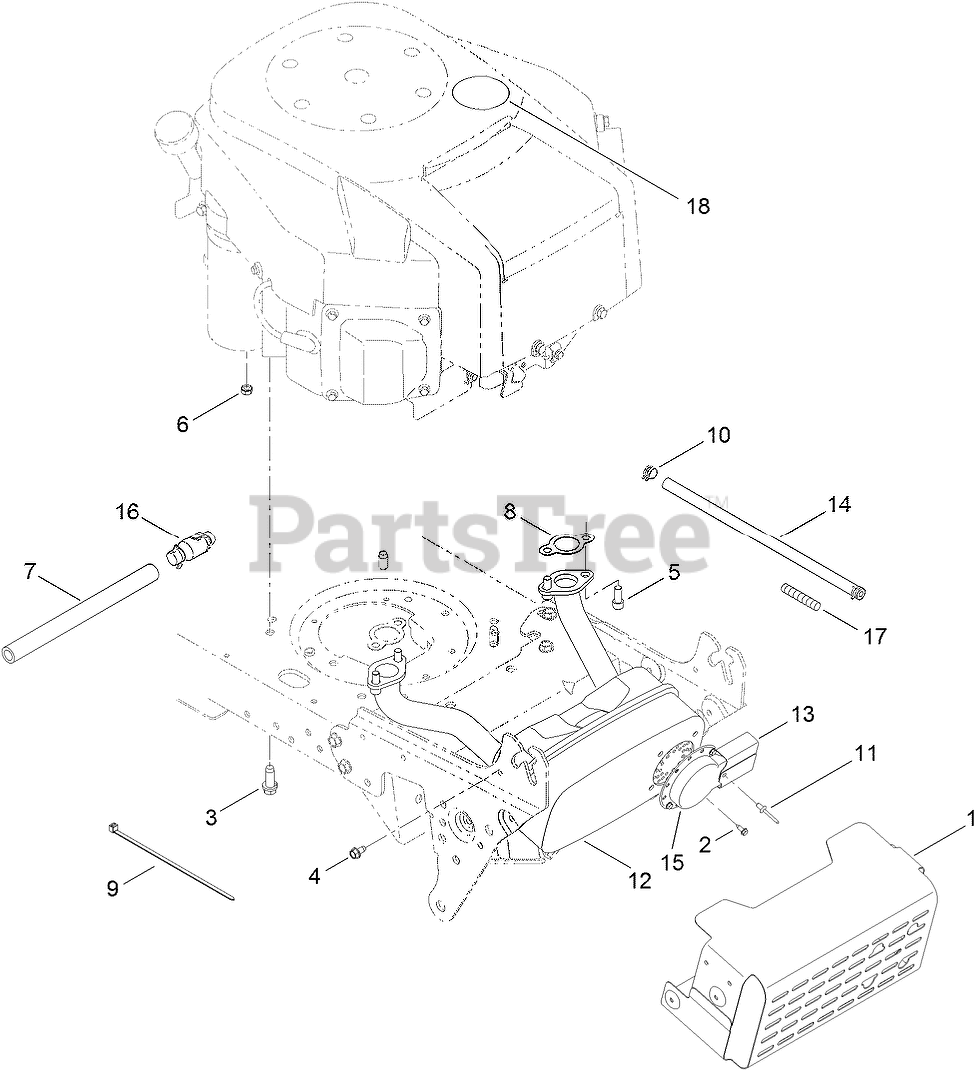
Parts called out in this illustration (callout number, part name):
1	SHIELD-MUFFLER
2	SCREW-HWHTF
3	SCREW-HH, TAP
4	SCREW-HWHTF
5	SCREW-HSH
6	NUT-SEMS
7	HOSE-DRAIN
8	GASKET-EXHAUST
9	TIE-CABLE
10	CLAMP-HOSE
11	RIVET-POP
12	MUFFLER-TWIN
13	DEFLECTOR-MUFFLER
14	HOSE-FUEL
15	DEFLECTOR-MUFFLER
16	DRAIN-OIL
17	HOSE-VENT
18	DECAL-CHECK OIL
